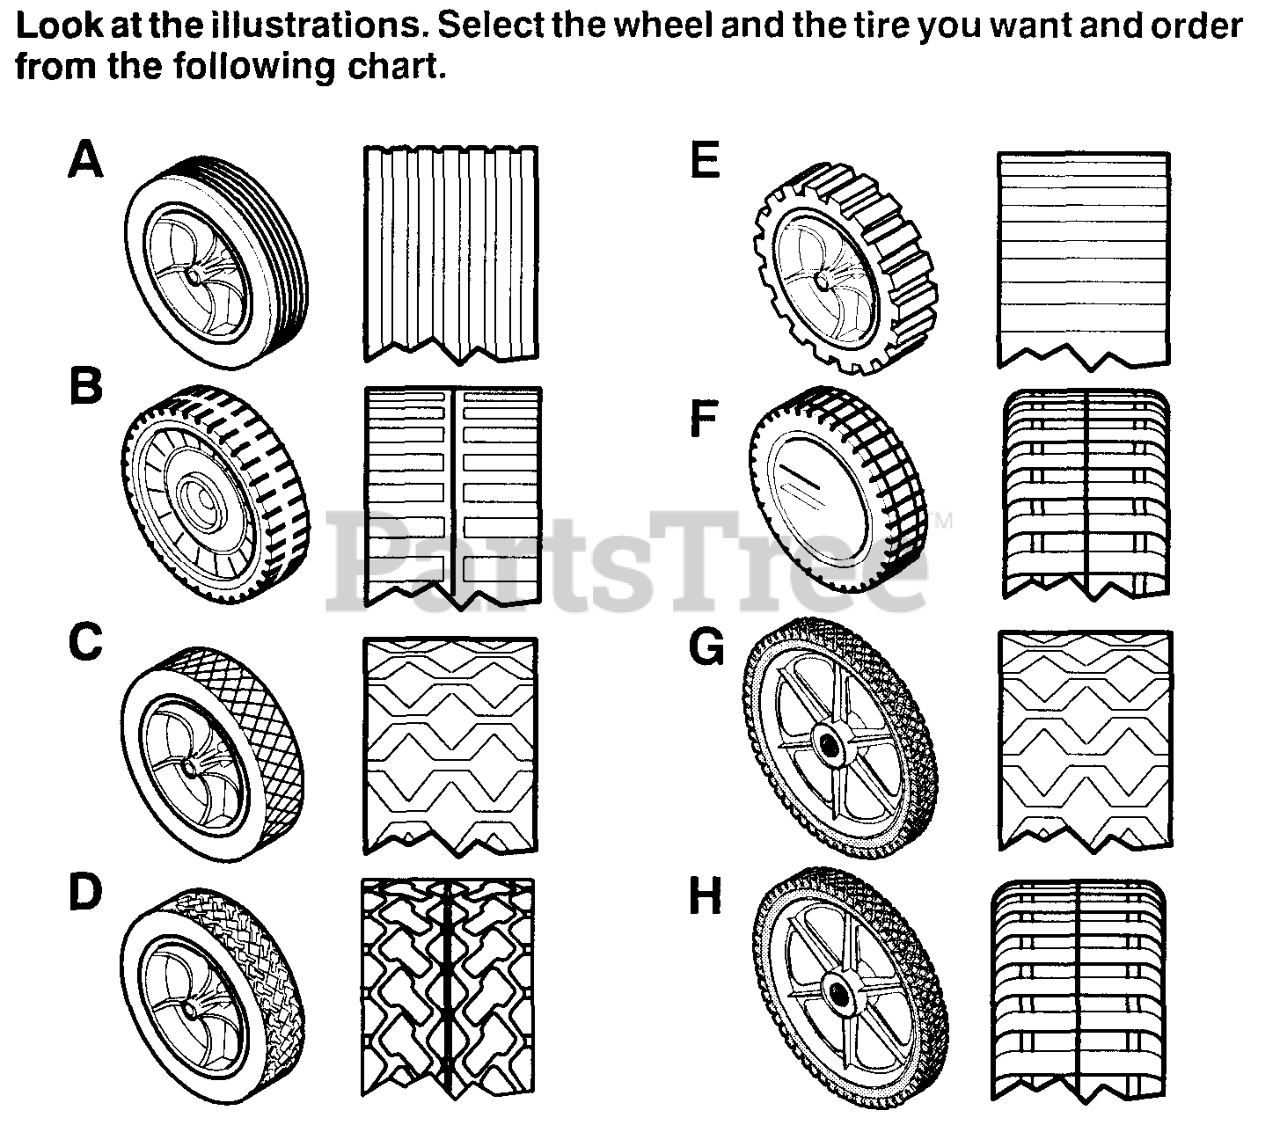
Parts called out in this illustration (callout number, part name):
A	WHEEL & TIRE ASSEMBLY, Light Gray, 8"
A	8-inch Plastic, Dark Gray
A	8-inch Metal, White
B	7-inch Plastic, White
B	7-inch Plastic, Light Gray
B	7-inch Plastic, Dark Gray
C	6-inch Plastic, White
C	7-inch Plastic, White
C	7-inch Plastic, Light Gray
C	7-inch Plastic, Dark Gray
C	8-inch Plastic, White
C	8-inch Plastic, Light Gray
C	8-inch Plastic, Dark Gray
C	8-inch Metal, White
D	7-inch Plastic, White
D	WHEEL & TIRE ASSEMBLY, White, 8"
D	8-inch Plastic, Light Gray
D	8-inch Plastic, Dark Gray
E	WHEEL & TIRE ASSEMBLY, White, 8"
E	8-inch Plastic, Dark Gray
E	8-inch Metal, White
F	WHEEL & TIRE ASSEMBLY, White, 8"
F	8-inch Plastic, Light Gray
F	8-inch Plastic, Dark Gray
F	8-inch Ball Bearing, Light Gray
F	8-inch Ball Bearing, Dark Gray
G	14-inch, White
G	14-inch, Light Gray
G	14-inch, Dark Gray
G	WHEEL & TIRE ASSEMBLY, White, 14"
G	14-in, Ball Bearing, Light Gray
G	14-in, Ball Bearing, Dark Gray
H	14-inch, White
H	14-inch, Light Gray
H	14-inch, Dark Gray
H	WHEEL & TIRE ASSEMBLY, Ball Bearing, 14"
H	14-in, Ball Bearing, Light Gray
H	14-in, Ball Bearing, Dark Gray
